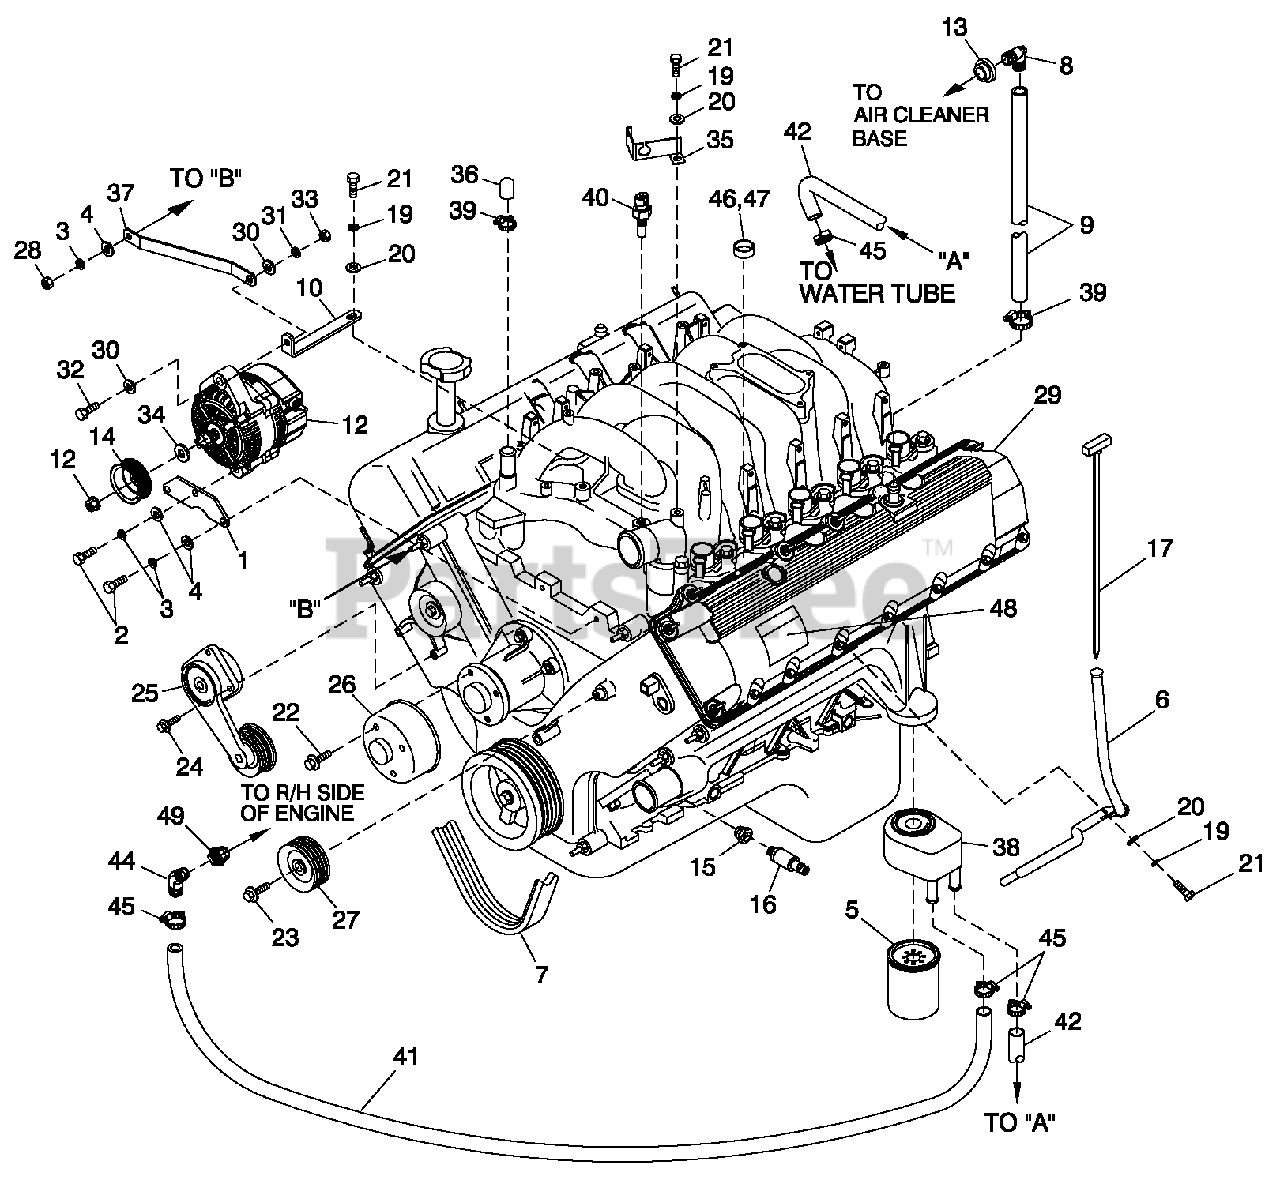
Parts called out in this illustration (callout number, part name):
1	BRACKET,D.C. ALTERNATOR LOWER
2	SCREW HHCM8-1.25X20G88
3	WASHER LOCK M8-5/16
4	WASHER FLAT 5/16-M8ZINC
5	OIL FILTER,FORDV-10ENGINE
6	DIPSTICKTUBE, FORD 6.8L
7	BELTSERPENTINE (65.0) LG) (1800 RPM)
8	BARBED EL 903/4 PLASTIC
9	HOSE 3 /4 1D SAE-30R2 (16.75' LG)
10	BRACKET DC ALTERNATORUPPER
11	HARN ENG &8L H-100 (USE WITH PROBE P/N 0E2507)
12	ALTERNATOR DC W/OUT PULLEY
13	GROM MET
14	PULLEY 80 OD DC ALTERNATOR (1800 RPM)
15	BUSHING REDUCER 3/8 TO 1/8 GAL
16	SENDER OIL PRESSURE 1/8" NPT
17	DIPSTICK6.8L FORD
18	TIEWRAP UL 7.4" X .19" BLK
19	WASHER LOCK M6-1/4
20	WASHER FLAT 1/4 ZINC
21	SCREW HHCM6-1.0X20 G88
22	BOLT WATER PUMP PULLEY
23	BOLT GROOVEDIDLERPULLEY
24	BOLT BELT TENSIONER
25	TENSIONER ENG. AUTOMATIC BELT
26	PULLEY WATER PUMP FORD (1800RPM UNITS)
27	PULLEYGROOVED ENGINEIDLER
28	NUT HEXM8-1.25 G8YELCHR
29	ENGINE G68LG3V-10
30	WASHER FLAT 3/8-M10ZINC
31	WASHER LOCKM10
32	SCREW HHC M 10-1.5 X 45 G 8.8 FT
33	NUT HEXM10-1.5 G8YELCHR
34	SPACER DC ALTERNATOR PULLEY
35	BRACKET SIGNAL CONDITIONER
36	CAP RUBBER
37	BRACKET DC ALT STABILIZER
38	OIL COOLER FORD (150KW3600RPM)
39	CLAMP HOSE #10 .56-1.06
40	TEMPERATURE SENDER DELPH
41	HOSE OIL COOLER PREFORMED 3/4(150KW3600RPM)
42	HOSEOIL COOLER (150KW3600RPM)
44	BARBED EL 451/2NPTX3/4OD
45	CLAMP HOSE #10 .56-1.06 (150KW3600RPM)
46	PLUG EXPANSION 14OD
47	ADHESIVE LOCTITE 620
48	DECAL EMISSION CTRL INFO 6.8L
49	ADAPTER 1/2"NPT X3/8"NPT
